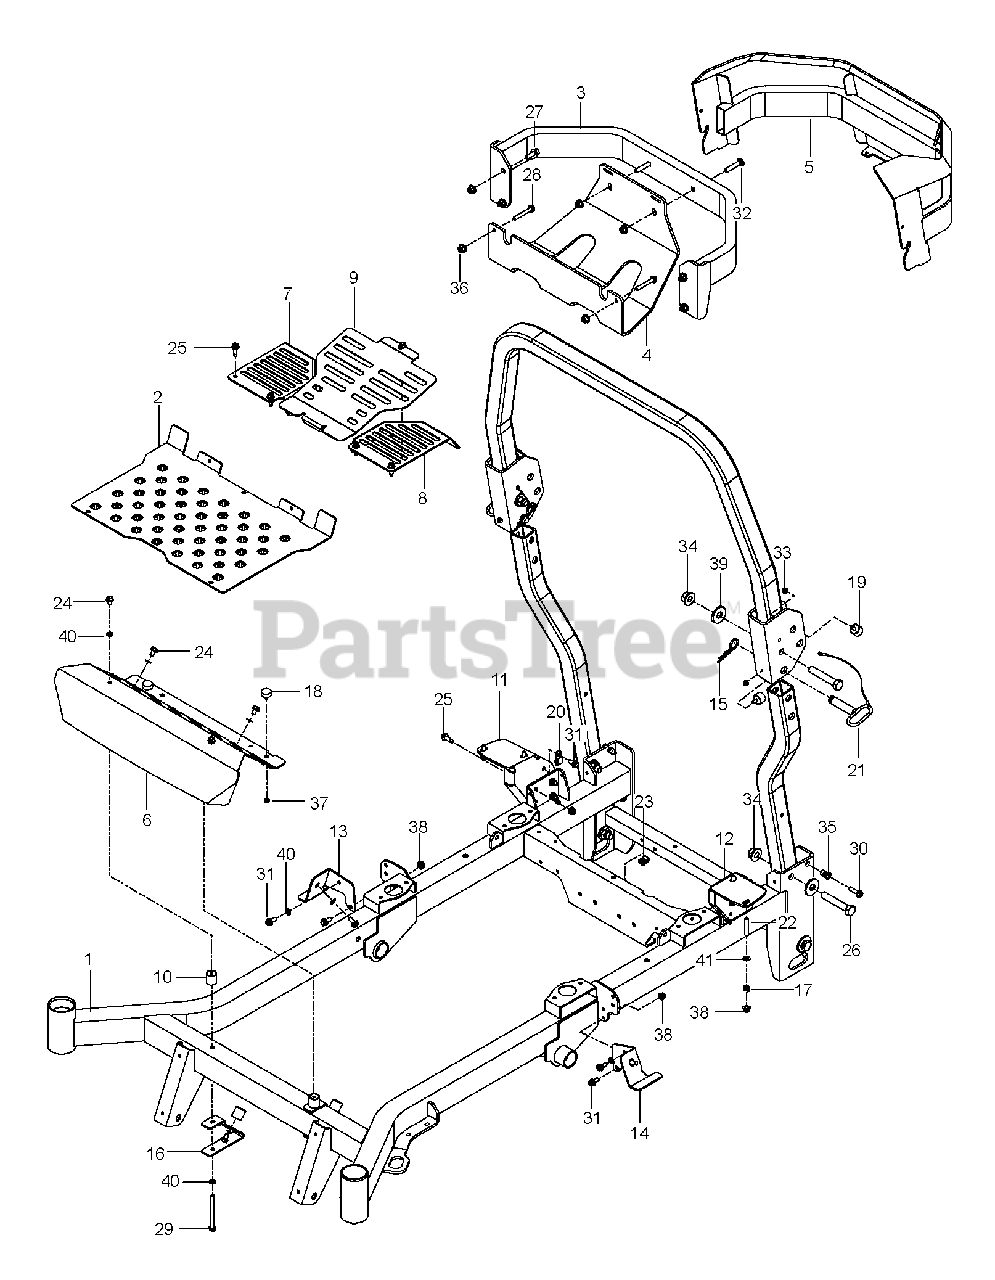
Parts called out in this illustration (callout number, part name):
1	FRAME W/DECALS, PZ
2	PLATE FLOOR PAN ORANGE
3	BUMPER, REAR, ORG
4	PLATE.SKID.GRAY
5	GUARD.ENGINE.GREY.498
6	PLATE, FOOT REST, OR
7	COVER, FAN RT BLK
8	COVER, FAN LT BLK
9	COVER, CENTER BLK
10	MOUNT, F/F INSERT
11	MOUNT, RT TANK, BLK
12	MOUNT, LT TANK, BLK
13	MOUNT, TANK, RT-BLK
14	MOUNT, TANK, LT-BLK
15	PIN HAIR .148 X 2-15/16 #210
16	BRACKET, REST MOUNT
18	BUMPER, 1/4-20 STUD, 1/4
19	BUMPER, MALE STUD, 1/4-20
20	DOUBLE TUBE CLAMP
22	STUD, 5/16C
23	U-CLIP 5/16-18 NUT RETAINER
24	SCR 5/16-18 X 1/2 SELFTAP ZN
25	RP BLT 5/16-18 X 1 THRD FORM D
26	5/8-11 X 3-1/2 HHB GRADE 5
27	HHFS 3/8-16 X 1 GRD 5 ZD
28	HHFS 5/16-18 X 2.25 GD 5
29	HHFS 5/16-18 X 3 3/4
30	HHFS 5/16-18 X 1.25 TPBLT GD 5
31	HHFS 5/16-18 X 3/4
32	RHSNB 3/8C X 2
33	LOCKNUT.NYLOC.1/4-20
34	NUT 5/8-11 FLG NYLOC ZD
35	NUTSERT 5/16-18 THICK GRIP
36	NUT 3/8-16 HEX FLG NYLOC ZD
37	JAM NUT 1/4C (2 2 PW01)
38	5/16-18 NYLOC FLANGE NUT
39	WASHER, 5/8 FLAT
40	WASH 5/16 DISC SPRING ZD
41	WASHER
